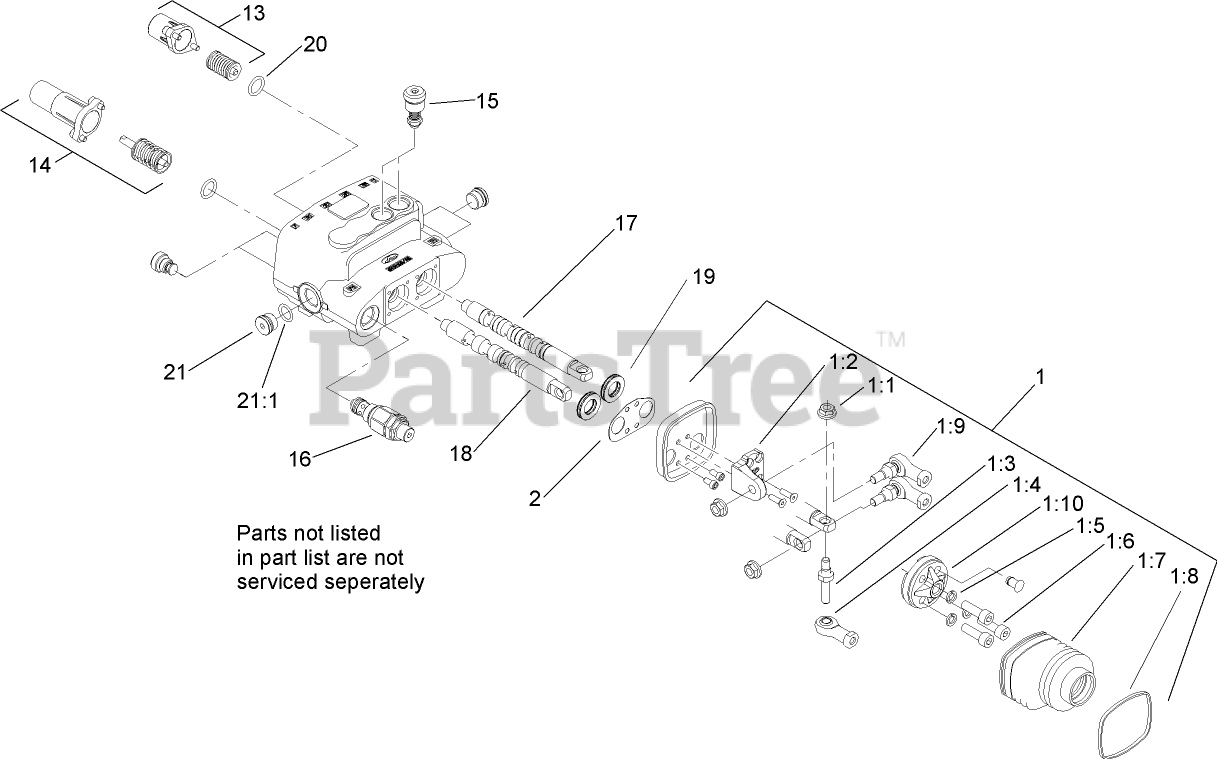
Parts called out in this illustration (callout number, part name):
1	JOYSTICK KIT
1:2	PIVOT-JOYSTICK
1:3	PIN-JOYSTICK
1:4	END-ROD
1:5	WASHER-LOCK, SPRING
1:6	SCREW-HSH
1:7	BELLOW-RUBBER
1:8	TIE-CABLE
1:9	JOINT-JOYSTICK
1:10	HOLDER-ARTICULATED
2	SEAL-JOYSTICK
13	VALVE SPRING KIT
14	DETENT SPRING KIT
15	VALVE-RELIEF
16	VALVE-RELIEF, MAIN
17	SPOOL-VALVE
18	SPOOL-VALVE
19	SEAL-VALVE, SPOOL
20	SEAL-VALVE
21	PLUG-HEX
21:1	O-RING
